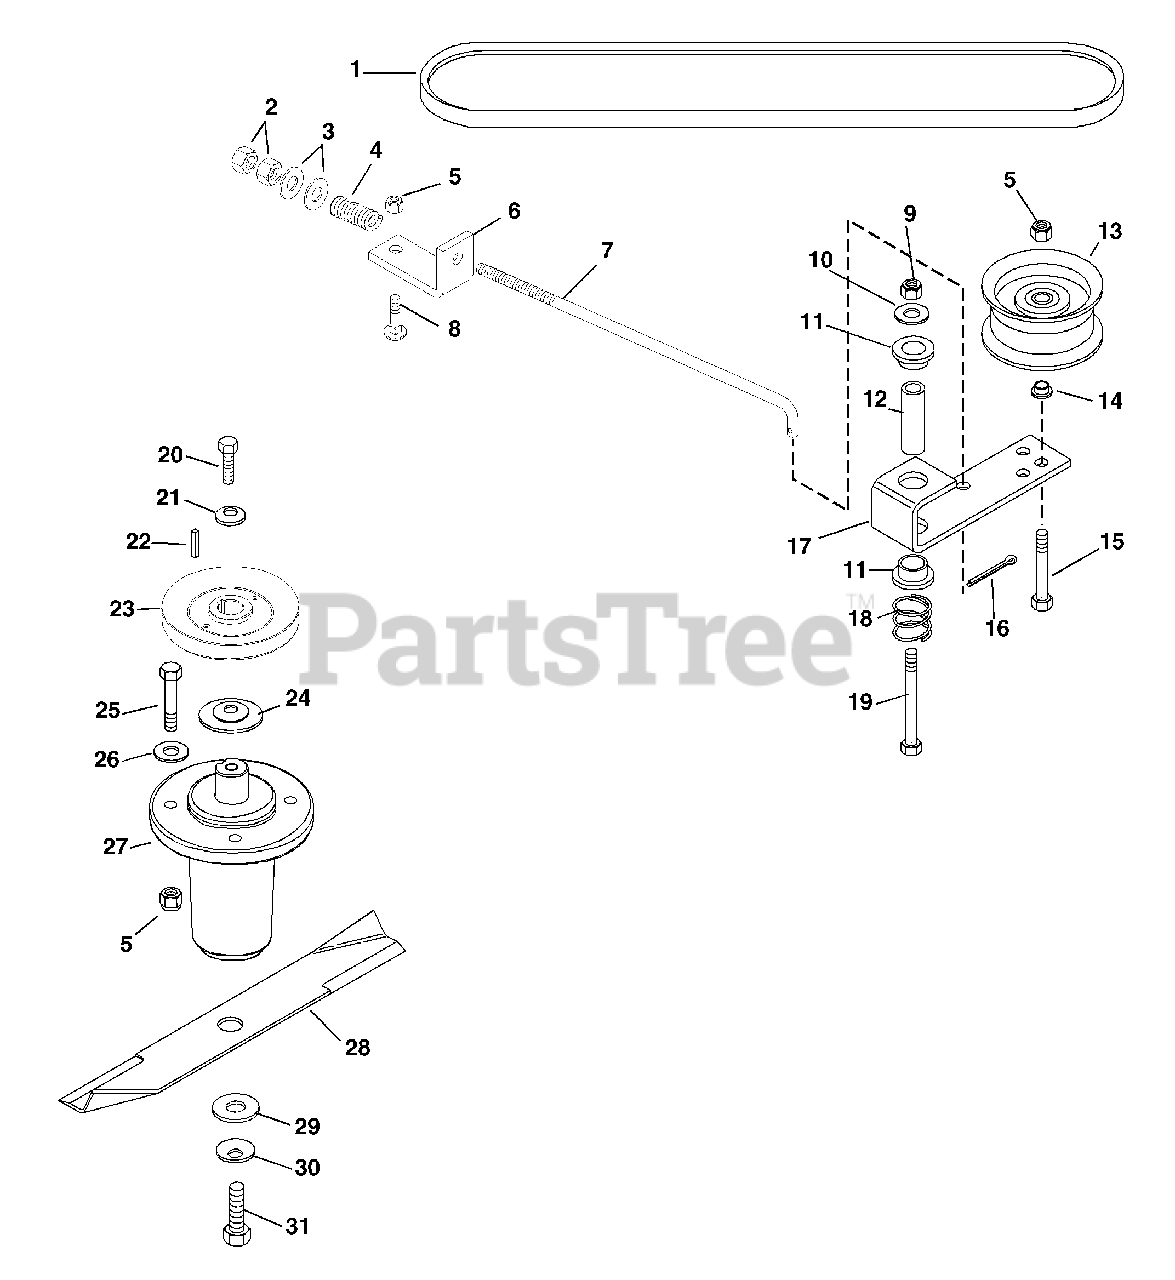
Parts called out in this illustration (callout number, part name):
1	V-Belt, Wrapped 50"
2	Nut-Hex .375-24 Grade 2
3	Washer-Flat-Steel .406 x .812 x .065
4	Compression Spring, .085 x .80 x 1.00
5	Nut, Locking Center .38-16
6	Bracket, Belt Tensioner
7	Rod, Idler
8	Bolt, Round Head Square Neck .38-16 x 1.00
9	Nut, Locking Center .50-13
10	Washer, Flat-Steel .531 x 1.25 x .10
11	Bushing, Flanged .762 x 1.00 x .580 x 1.48
12	Spacer .560 x .750 x 2.437 Steel
13	Idler-Flat
14	Bushing-Flanged .406 x .88 x .270 x .140
15	Bolt-Hex .38-16 x 2.25 Grade 5
16	Pin-Cotter .09 x .75
17	Arm, Idler Pivot
18	Compression Spring, 1 x .78 x .338
19	Bolt-Hex .50-13 x 3.25 Grade 5
20	Bolt-Hex .38-16 x 1.00 Grade 8
21	Washer-Cupped-Serrated .375
22	Key-Square .25 x 1.00 x .25
23	Weldment, Pulley 4.75 x 1.004 w/key
24	Slinger-Dust
25	Bolt-Hex .38-16 x 1.25 Grade 5
26	Washer-Flat-Steel .438 x 1.00 x .083
27	Assembly-Spindle
28	Blade, 36" Tungsten
29	Washer-Flat .640 x 1.81 x .250
30	Washer-Bellville .63 x 1.625 x .14
31	Bolt-Blade
